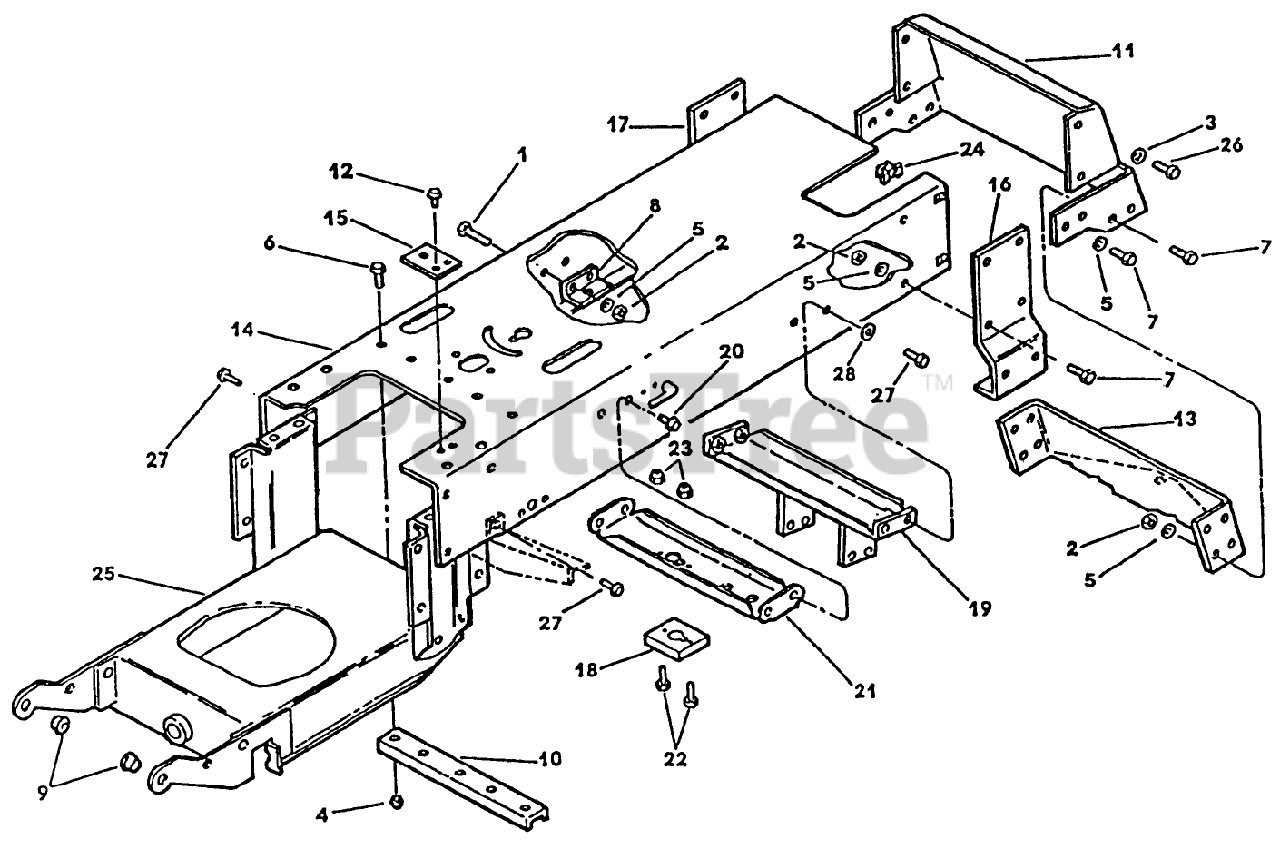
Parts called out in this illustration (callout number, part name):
2	NUT
4	NUT
5	WASHER
9	BEARING-NYLINER
18	BRACKET-SUPPORT *B
21	SUPPORT *B
22	SCREW
23	NUT-LOCK, CONE
24	NUT-SQ, CAGED
26	SCREW
